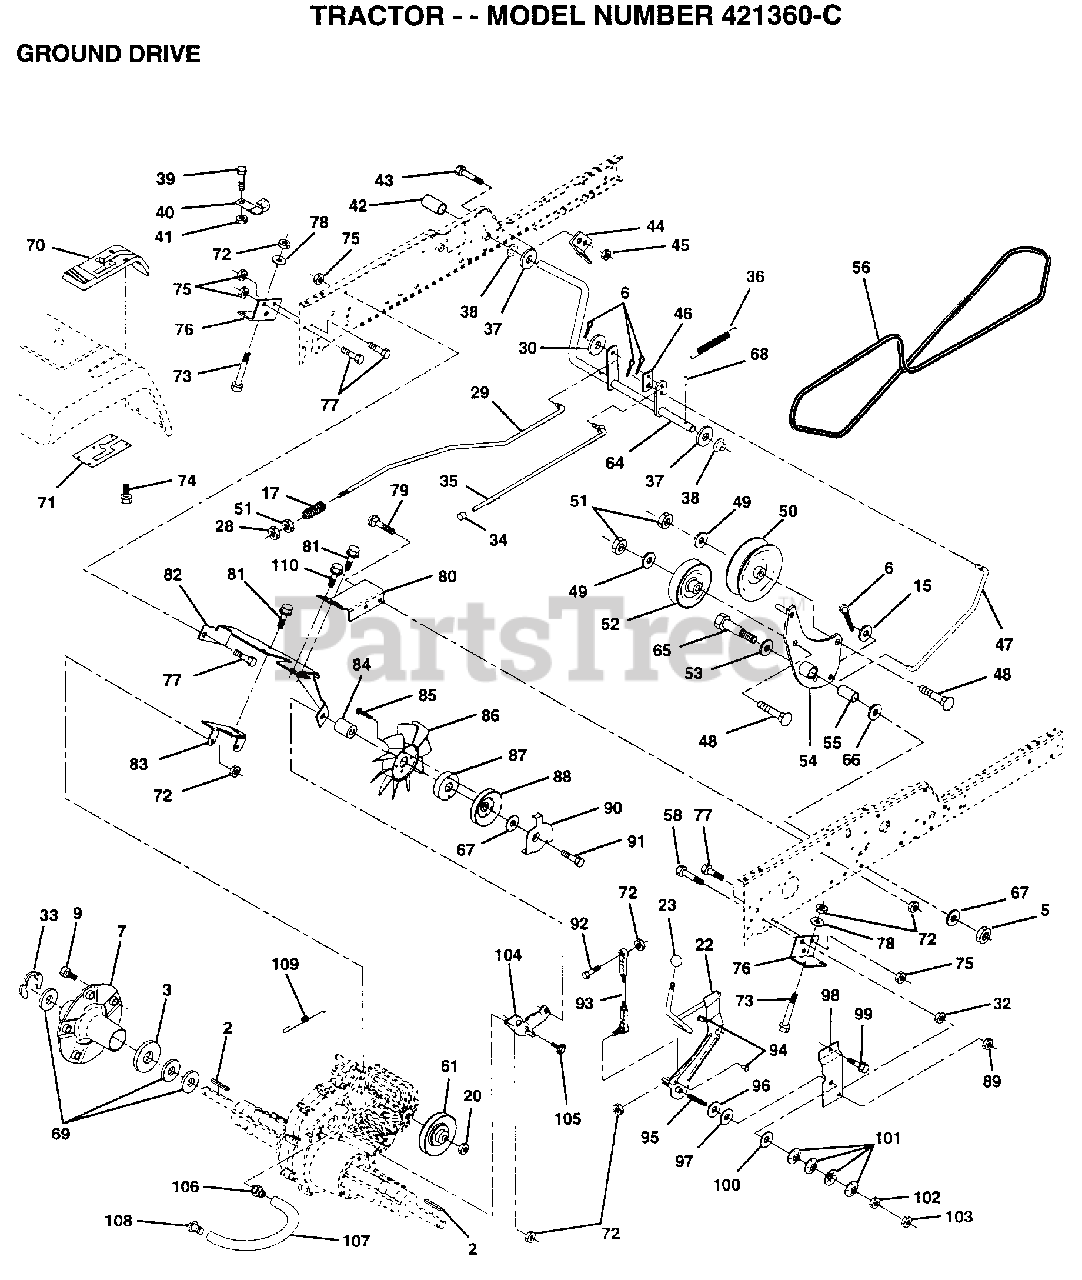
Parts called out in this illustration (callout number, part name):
2	KEY 1/4 X 2.5
3	WASHER T
6	COTTER PIN
7	HUB WHEEL ASM
9	BOLT.HUB.WHL.REAR
15	WASHER
17	SPRING ROD BRAKE
22	SHAFT ARM ASM
23	KNOB DLX BLK/BLK
28	NUT
29	ROD BRAKE
30	WASHER
32	NUT
33	E RING HYT
34	PLUNGER CAP T
35	ROD BRAKE PART GT
37	WASHER
38	NYLINER T
39	SCREW
40	ACT-SWITCH T
42	PEDAL COVER T
43	BOLT LT
44	BRKT SWITCH GT
45	NUT
46	RETAINER.SPRING
47	ROD.CLUTCH
48	BOLT
49	WASHER
51	NUT
52	PULLEY.IDLER.V.GR
53	WASHER T
54	ARM.ASM.IDLER.CLU
55	"LY, BEARING"
56	BELT-V 84.5
58	BOLT
59	FLAT IDLER PULLEY
61	PULLEY TRANSAXLE
65	AXLE BOLT
66	WASHER.HARD.BLADE
67	WASHER
68	ROLL PIN STD
69	WASHER
71	PLATE CONSOLE S
72	NUT
73	BOLT FIN HEX 5/16
74	SCREW HEXWSH H-L
75	NUT.7/16
76	BRACKET TRAN VGTH
77	BOLT
78	WASHER
79	BOLT
80	BRACKET TORQUE RH
83	STRAP TORQUE MID
84	SCREW
84	SPACER
85	SCREW YTV
86	"FAN 7"" HYDRO"
87	ADAPTER FAN
89	NUT GTV
90	KEEPER BELT
91	SCREW.HXWSH.3/8
93	LINK ASM SHIFT
94	XMAS TREE FASTNER
95	SCREW SET 5/16
96	WASHER NICKEL PLT
97	BEARING THRUST
98	BRACKET SHIFT
99	SCREW LT
100	WASHER COMPRESSIN
101	WASHER
102	NUT HEX NYLOCK
103	JAM NUT TI
104	BRACKET IDLER
105	SCREW CRT
109	SPRING BRAKE
110	HINGE SCREW
